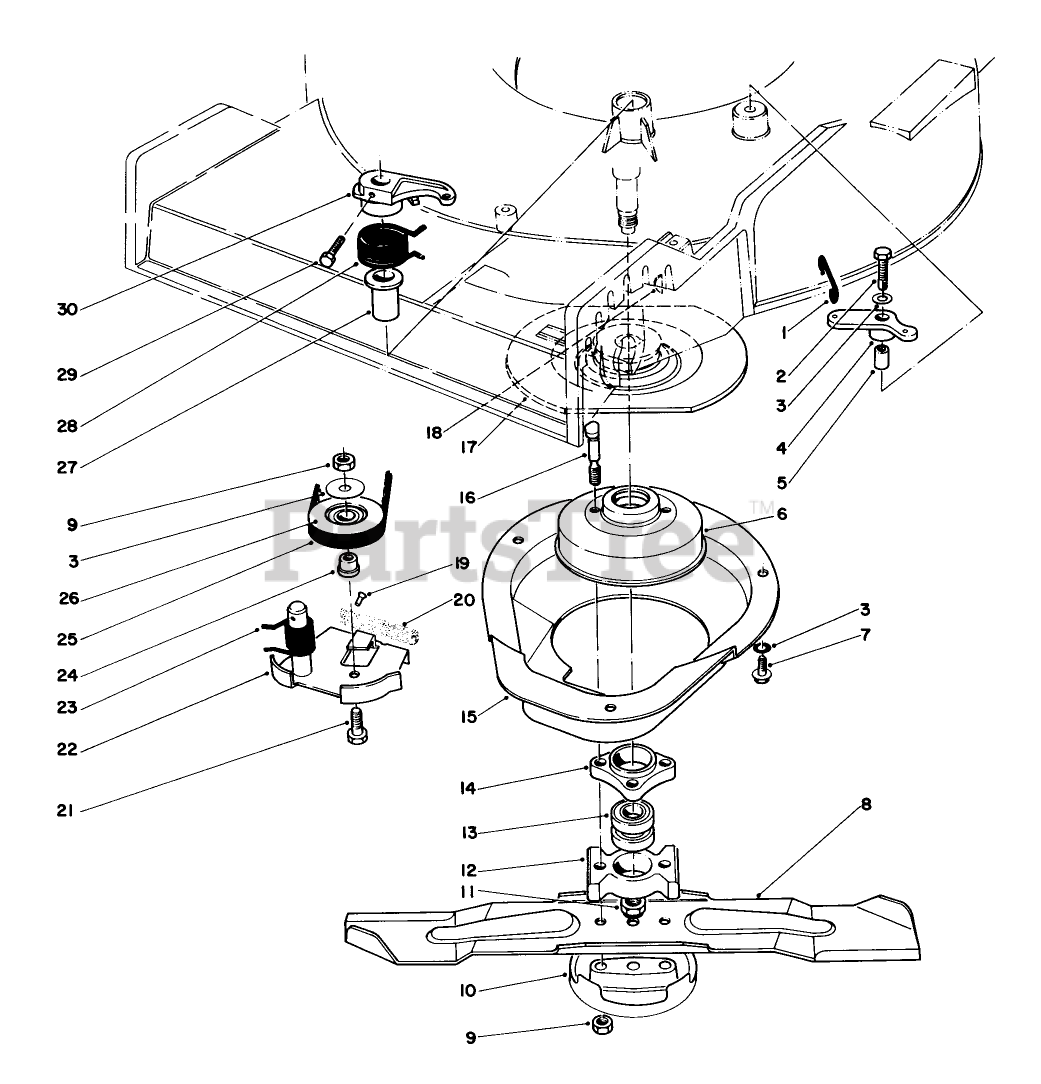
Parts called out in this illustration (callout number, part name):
2	SCREW-HH
3	WASHER-FLAT
7	SCREW-THD ROLL, HWH
9	NUT-LOCK, NI
11	NUT-LOCK, NI
13	BEARING-BALL
14	HUB ASM
16	BOLT-BLADE
18	KEY-WOODRUFF
19	.185 DIA X .375 RT +
21	SCREW-HH
23	SPRING-TORSION
24	HUB-PULLEY, IDLER
27	BUSHING PM
29	SCREW-HWH THD CUT
30	DISC. SEE PRCNOTES
